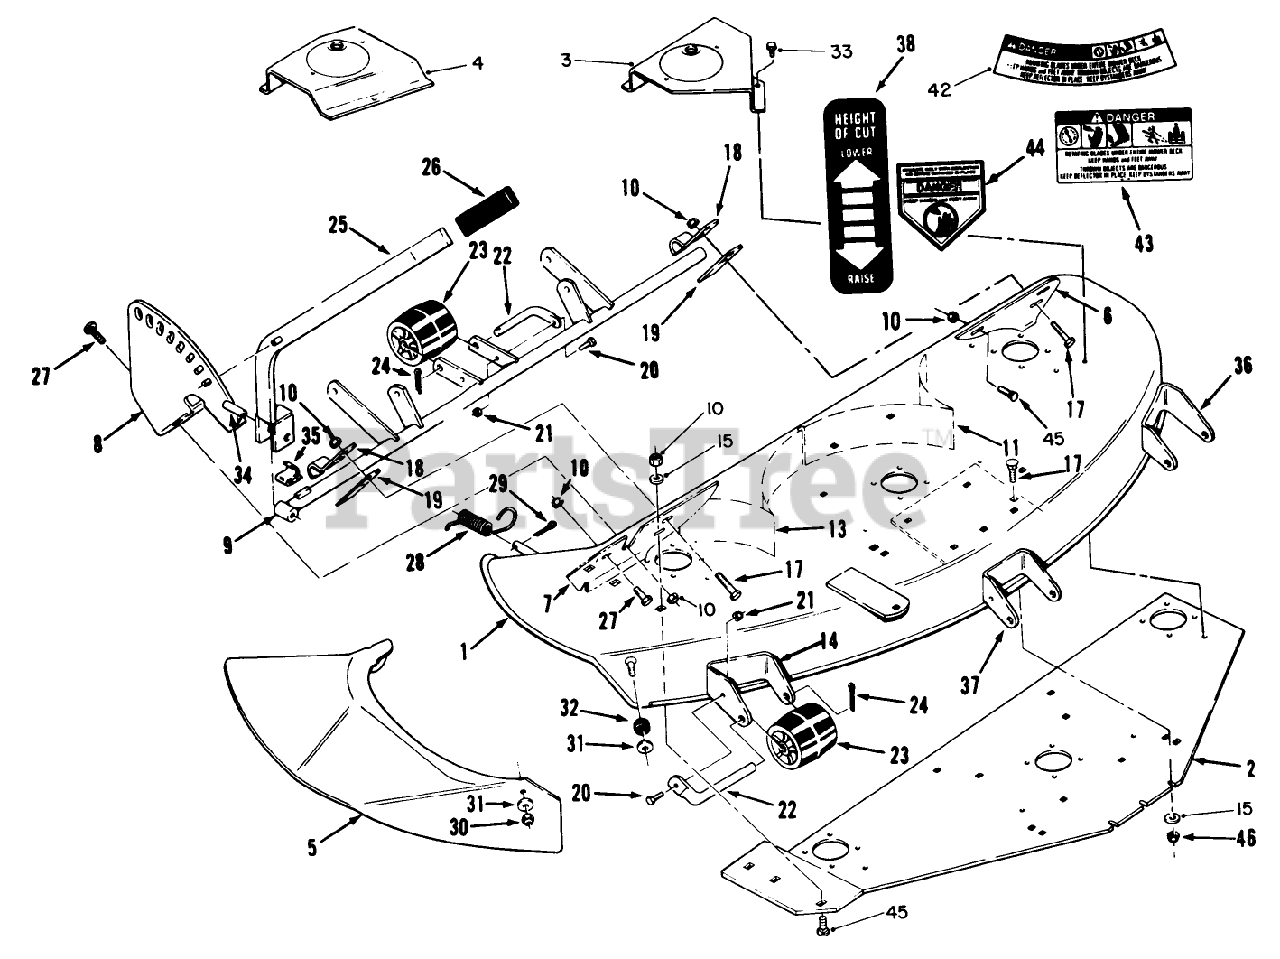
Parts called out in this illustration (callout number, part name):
6	PLATE-WEAR L.H. *R
10	NUT-LOCK, NI
13	BAFFLE-DECK RH
15	WASHER-FLAT
17	SCREW-CARR
20	SCREW-HH
21	NUT-LOCK, NI
22	ROLLER-SHAFT
24	PIN-COTTER
27	BOLT-CARR
29	PIN-COTTER
32	BUSHING-PIVOT
33	Bolt
34	SPIROL PIN
35	CLIP-SPRING
36	BRKT-ROLLER
38	DECAL-HOC
42	DECAL - DANGER
43	DECAL-DANGER, THROWN OBJECT
45	BOLT-CARR
46	NUT-LOCK, NI
